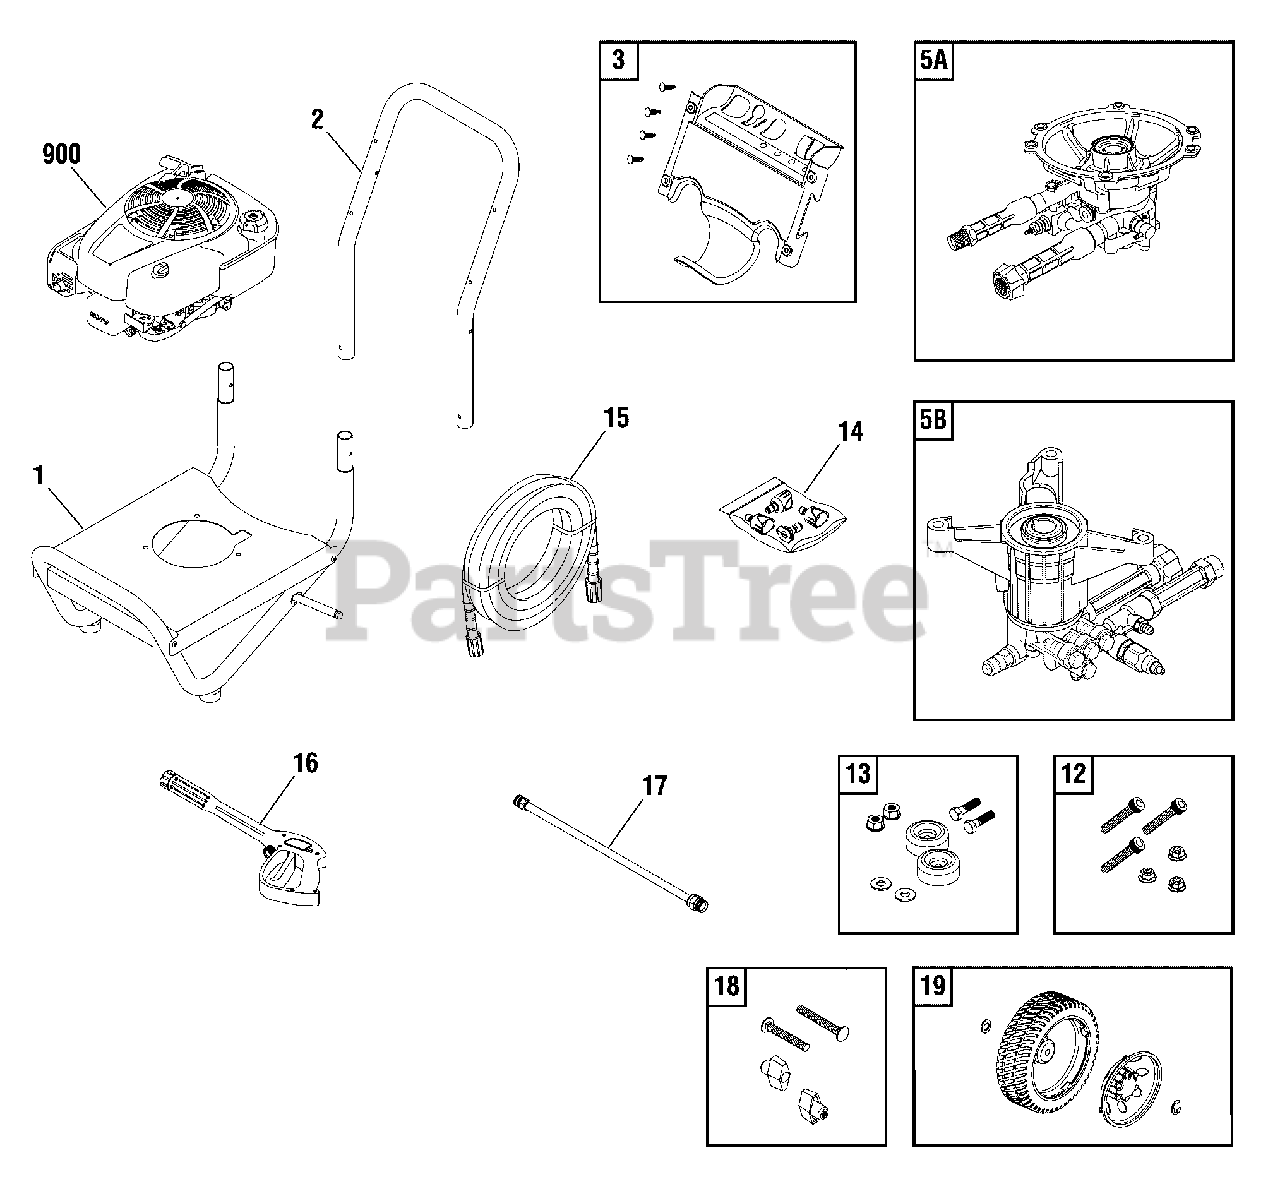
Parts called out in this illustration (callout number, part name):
3	BILLBOARD
5A	PUMP
12	KIT, Hardware, Pump Mounting
13	KIT, Vibration Mount
14	KIT, QC Nozzles
16	GUN
17	EXTENSION, QC
18	KIT, Hardware Handle
19	KIT, Wheel
900	*ENGINE
